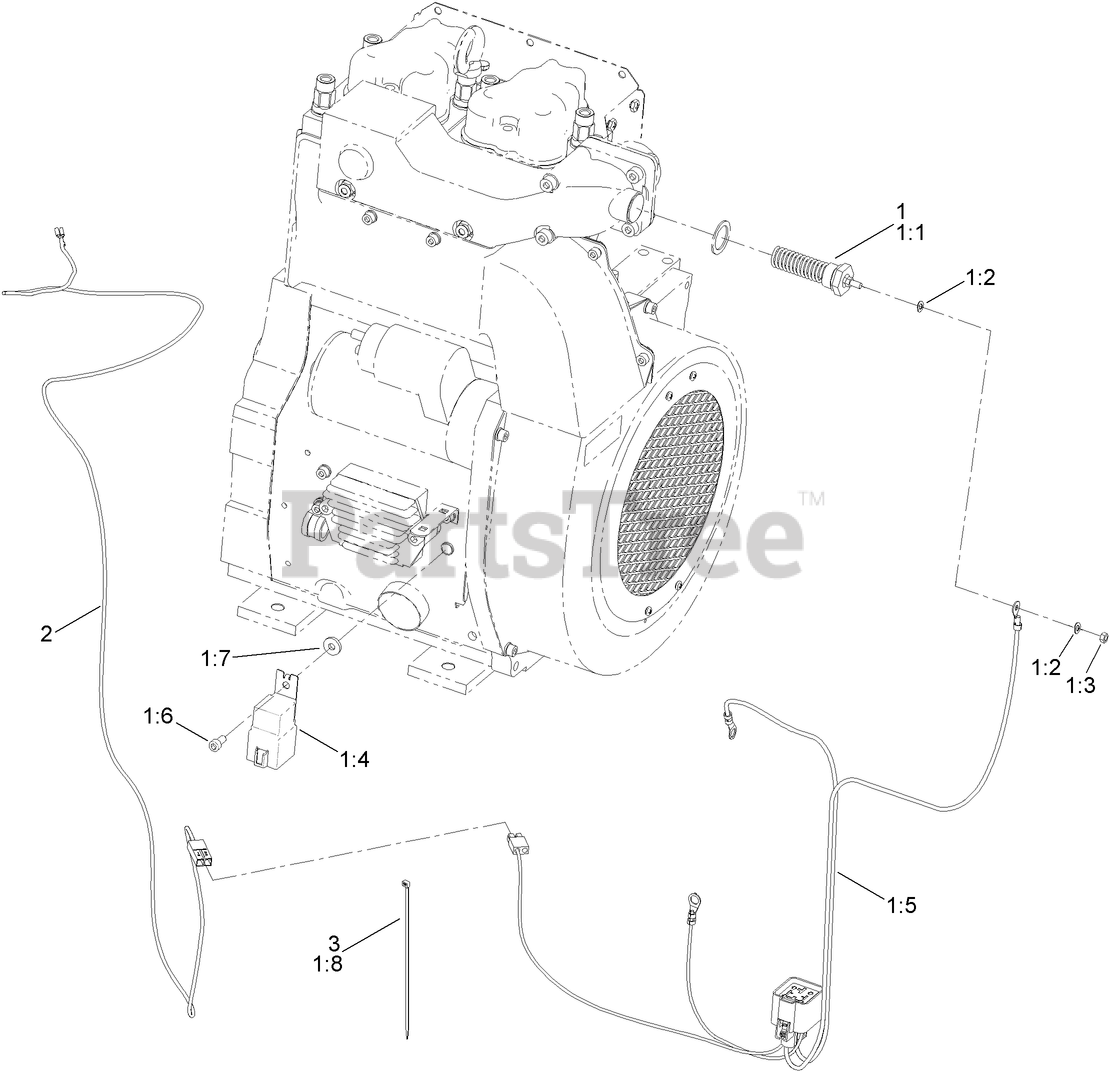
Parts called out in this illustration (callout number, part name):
1	GLOW PLUG ASM
1:1	PLUG-GLOW
1:2	WASHER-LOCK, SPRING
1:3	NUT-HEX
1:4	RELAY-70A
1:5	HARNESS-WIRE, GLOW PLUG
1:6	SCREW-HHF
1:7	SPACER
1:8	TIE-CABLE
2	HARNESS-WIRE, SIGNAL (PRE-HEATER)
3	TIE-CABLE
